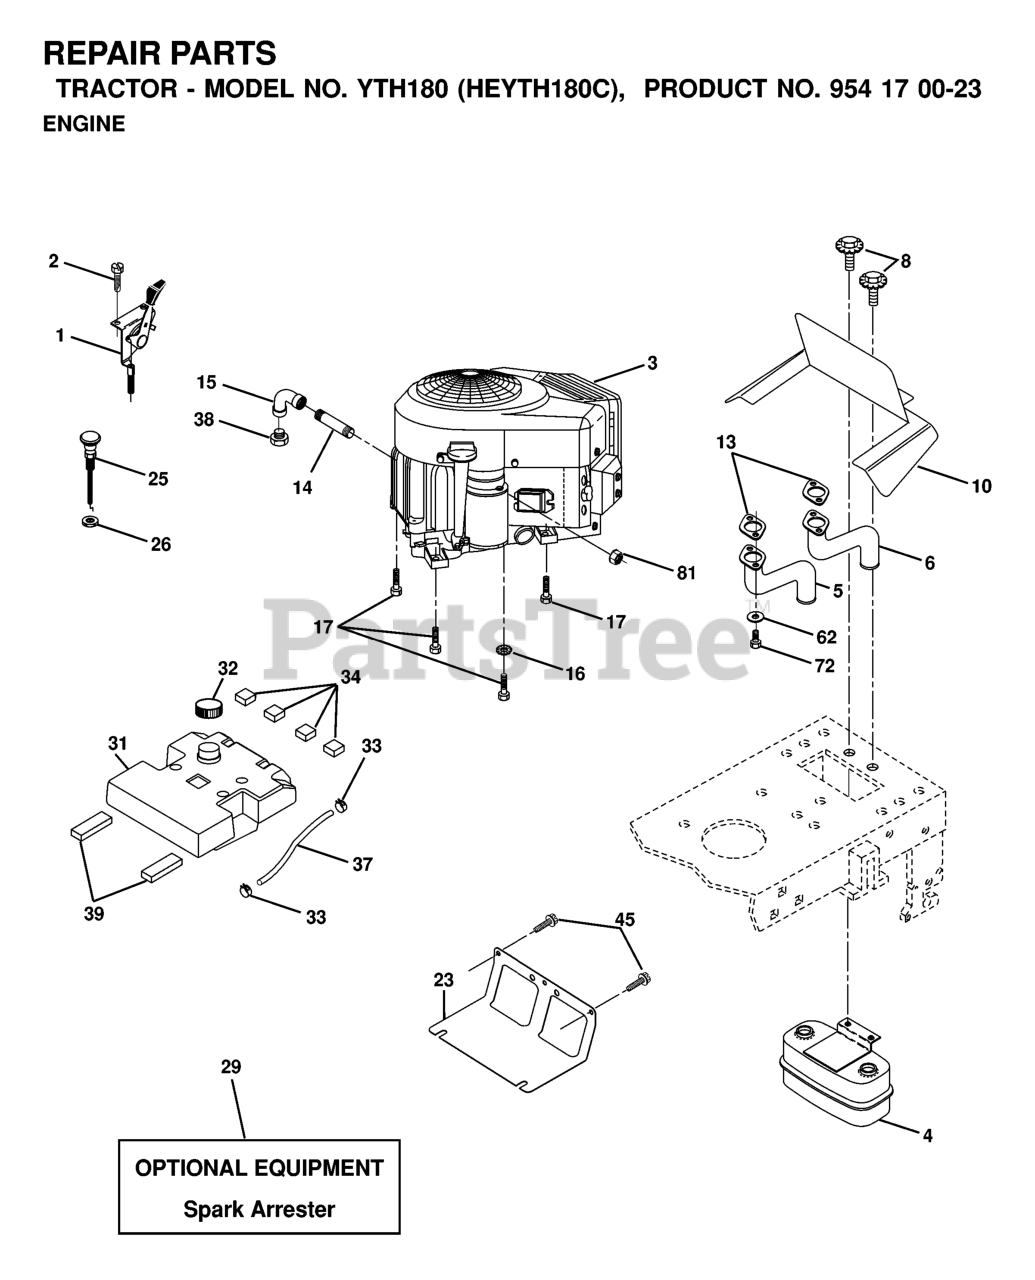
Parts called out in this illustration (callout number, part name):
1	CONTROL THROTTLE 36"
2	SCREW LT
4	MUFFLER.TWIN.CYL.LOW.TONE
5	RP.EXHAUST.TUBE.LH.BS/TWIN
6	EXHAUST.TUBE.RH.BS/TWIN
8	BOLT HEX WASHER HD 5/16-18
10	SHIELD.BROWNING.B&S
13	GASKET.MUFFLER
14	Nipple, Pipe 3/8 NPT x 4-1/2
15	ELBOW
16	LOCKWASHER
17	SCREW LT
23	SHIELD.BROWNING.DBR.GUARD
25	CONTROL, CHOKE
26	Nut Keps 3/8 - 24 UNF
29	KIT.SPARK ARRESTOR 794945 B&S
31	TANK.FUEL(3.5.GAL)
32	FUEL CAP
33	HOSE CLAMP
34	PAD-SPACER LT
37	HOSE T
39	PAD IDLER TI
45	SCREW 3/8-16X3/4
62	WASHER.LOCK.HVY.HLCL.SPR.5/16
72	SCREW
81	NUT FLANGE 1/4-20 STARTER NUT
